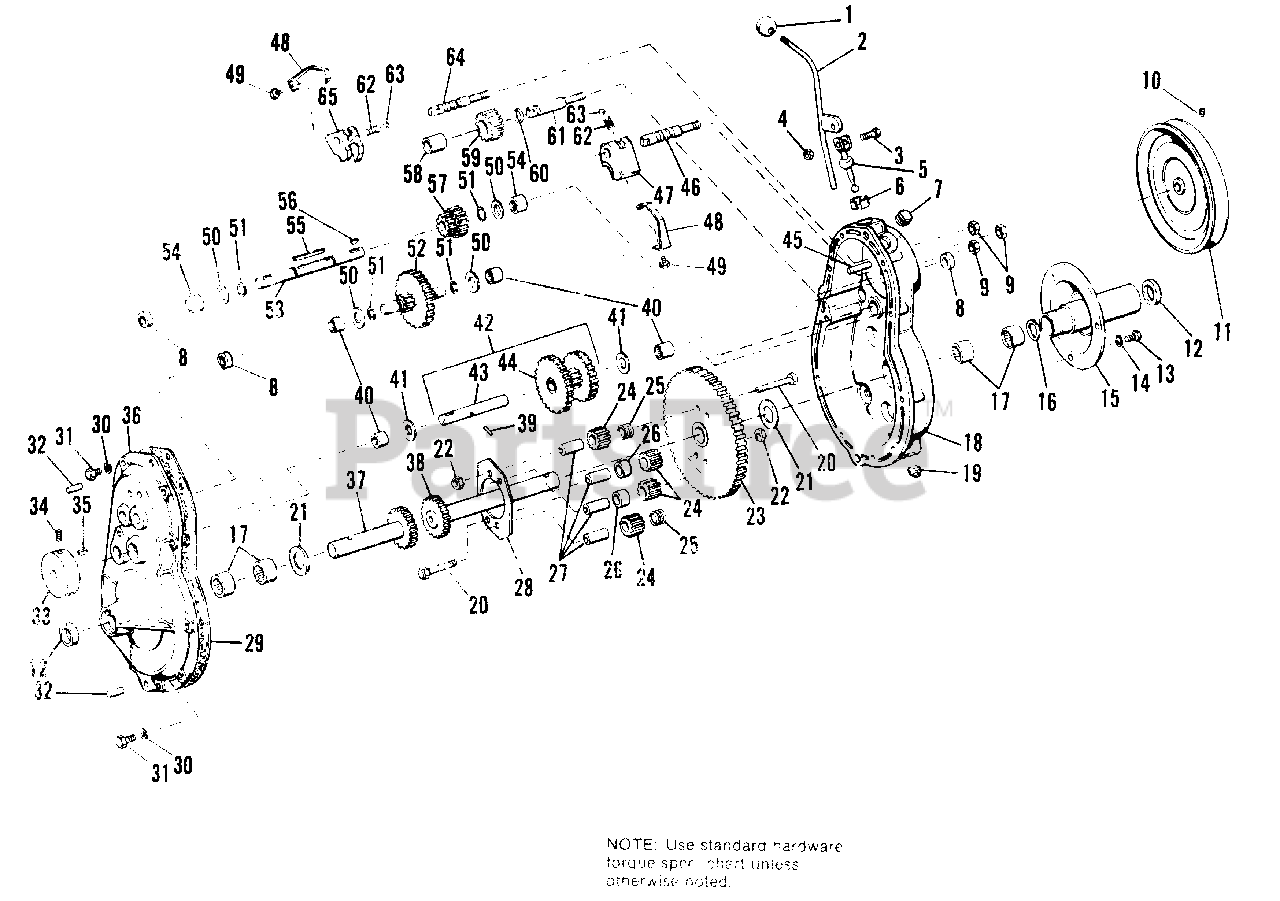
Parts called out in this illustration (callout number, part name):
2	ROD ASSY., Shift
3	CAPSCREW, Hex Hd., 1/4-20 x 3/4
4	LOCKNUT, Hex, 1/4-20
5	ROD ASSY., Shift
6	BUSHING, Half
9	NUT, Hex, Full, 7/16-14
10	SETSCREW, 3/8-24 x 3/8
13	CAPSCREW, Hex Hd., 3/8-16 x 7/8
14	LOCKWASHER, 3/8
15	HOUSING ASSY., Axle
17	BEARING, Roller
18	CASE ASSY., Gear
19	PLUG, Pipe, 3/8
20	CAPSCREW, Hex Hd., 3/8-16 x 2-1/2
22	LOCKNUT, Hex, 3/8-16
23	GEAR ASSY., Drive
24	PINION, Diff.
26	SPACER, Diff.
27	SPINDLE, Diff.
28	PLATE, Diff.
30	LOCKWASHER, 5/16
31	CAPSCREW, Hex Hd., 5/16-18 x 1-1/4
32	PIN, Roll, 3/8 x 1
33	DRUM, Brake
34	SETSCREW, 5/16-18 x 1/2
36	COVER ASSY., Gear Case
37	SHAFT ASSY., Axle, L.H. (990645 & 990646 Only)
37	SHAFT ASSY., Axle, L.H.
38	SHAFT ASSY., Axle, R.H.
38	SHAFT ASSY., Axle, R.H. (990645 & 990646 Only)
39	PIN, Dowel
40	BEARING, Roller
42	SHAFT & GEAR ASSY.
43	SHAFT & BRAKE
44	GEAR ASSY., Cluster
45	PIN ASSY., Roll
46	SHAFT, Shift, Hi-Lo
47	FORK, Shift, I & II
49	SCREW, Hex, Washer Hd., 5/16-18 x 5/16
51	RING, Retaining
52	GEAR & SHAFT ASSY.
53	SHAFT, Pulley, P.T.O.
54	BEARING, Roller
57	PINION ASSY., Hi-Lo
58	BEARING, Roller
59	PINION, Reverse
61	SHAFT, Pinion, Reverse
62	SPRING (990645 & 990646 Only)
63	BALL, Shift Lock
64	SHAFT, Shift, Reverse
65	FORK, Shift, Reverse
